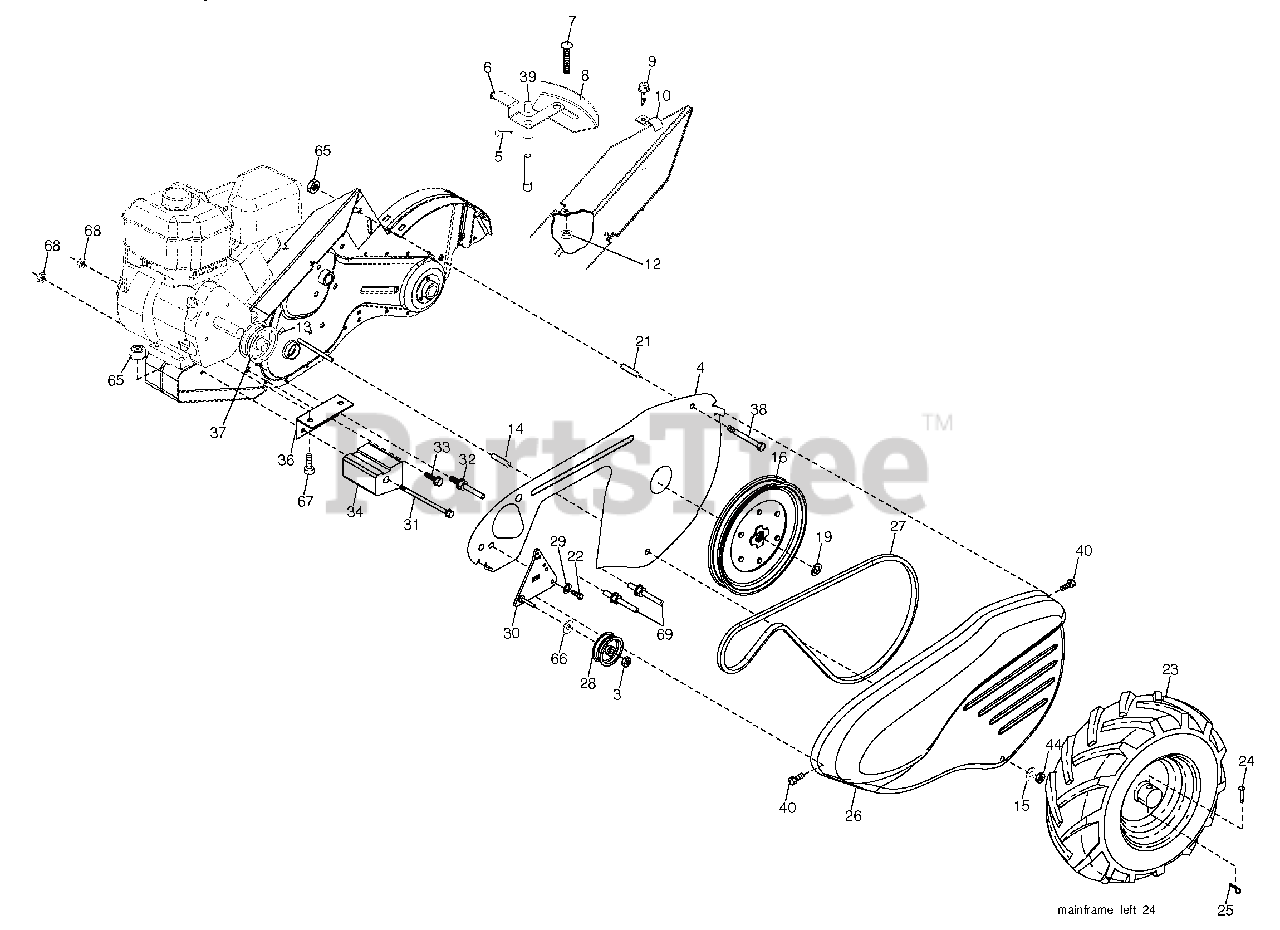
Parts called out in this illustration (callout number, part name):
3	Nut, Hex 3/8-16
4	Shield, Inner Belt Guard RT
5	Screw, Shift Lever
6	Lever, Shift
7	Bolt, Carriage 1/4-20 x 1/2 Gr. 5
8	Plate, Shift Indicator
9	Screw, Hex, Washer Head, Slotted #10-24 x 1/2
10	Clip
12	Nut, Keps Hex 1/4-20 unc
13	Screw, Set, Hex 5/16-18 x 3/8
14	Spacer, Split 0.327 x 0.42 x 1.220
15	Washer 11/32 x 11/16 x 16 Ga.
16	Sheave, Transmission
19	Retainer, Ring
21	Spacer, Split 0.327 x 0.42 x 2.09
22	Bolt, Fin Hex 5/16-24 unf x 1/2
23	Tire
23	Rim
23	Tire Valve
24	Rivet, Drilled
25	Clip, Hairpin
26	Guard, Belt
27	Belt, V
28	Pulley, Idler
29	Ring, Klip
30	Bracket, Idler
31	Bolt, Hex 5/16-16 x 12
32	Shaft, Idler Arm
33	Bolt, Hex 3/8-16 x 1
34	Counterweight, L. H.
35	Bolt, Hex 5/16-18 x 1-3/4
36	Bracket, Reinforcement, L. H.
37	Sheave, Engine
38	Bolt, Fin Hex 5/16-18 unc x 2-3/4
39	Cap, Plunger Blk
40	Screw Hex Wsh Slt #10-24 x 1/2
44	Nut Lock Hex w/Ins 5/16-18 unc PL
65	Nut Lock Hex Flange
66	Washer 13/32 x 13/16 x 12 Ga.
68	Nut Keps Hex 3/8-16 unc
69	Keeper Belt Engine
